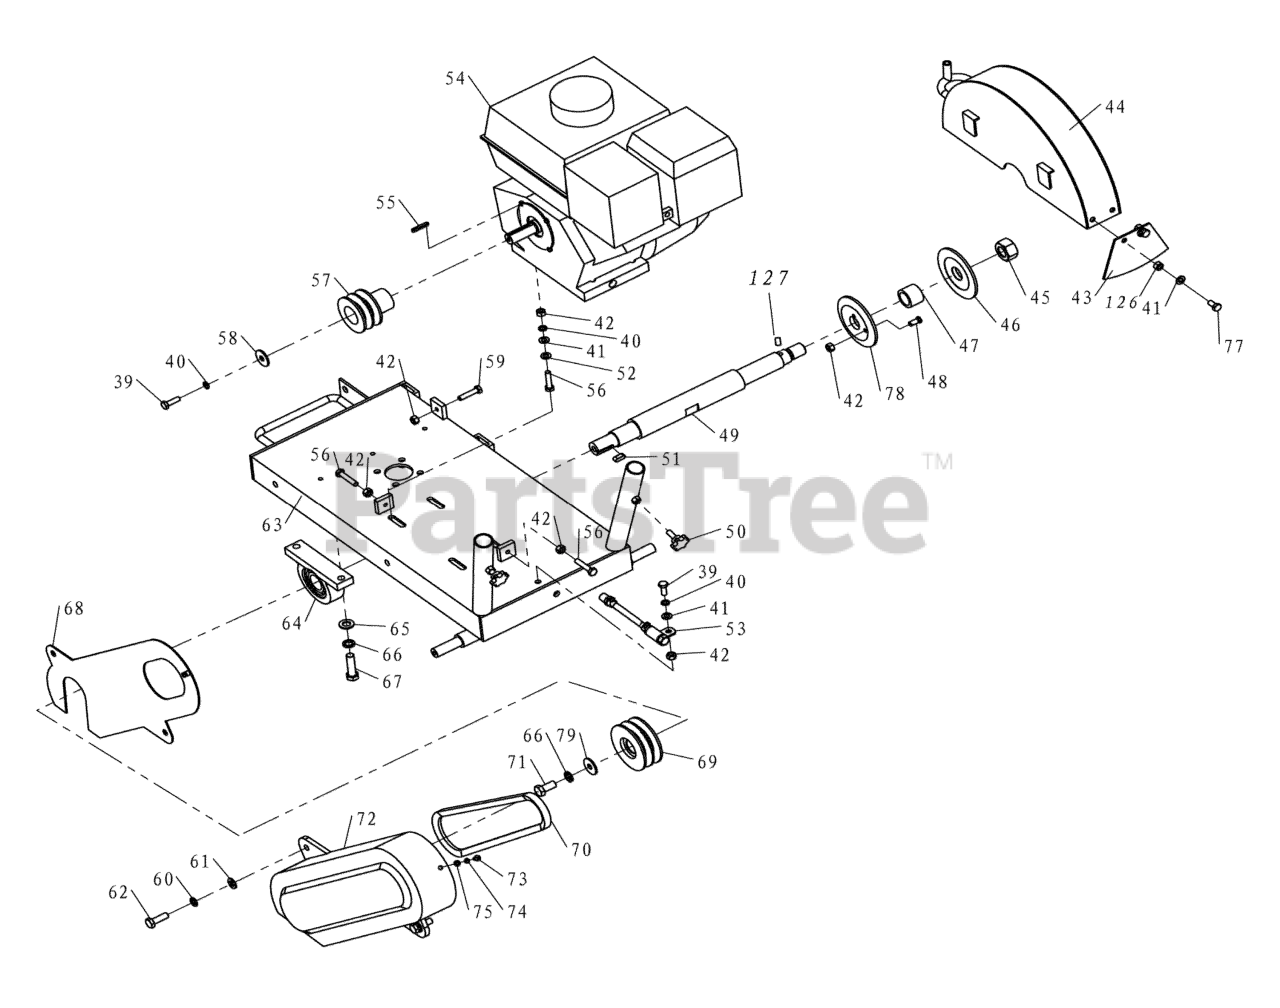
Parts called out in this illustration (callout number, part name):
39	BOLT, M8 x 25
40	WASHER, Spring, 8
41	WASHER, Flat, 8
42	NUT, M8
43	FENDER, Rubber
44	COVER, Blade
46	BLADE FLANGE
47	BUSHING, Blade
48	BOLT, Blade Location
50	KNOB BOLT
52	WASHER
53	DRAIN PIPE ASSEMBLY
54	ENGINE, Briggs & Stratton
56	BOLT, M8 x 45
57	PULLEY, Engine
58	KEY, Bushing
59	NUT, M10
60	WASHER, Spring, 10
61	WASHER, Flat, 10
62	BOLT, M10 x 30
63	BASE PLATE
64	BEARING, NSK206
65	WASHER, Flat, 12
66	WASHER, Spring, 12
67	BOLT, M12 x 45
68	COVER, Belt, Inner
69	PULLY, Belt
71	BOLT, M12 x 25
72	COVER, Belt, Outer
73	SCREW, Cross Recess Head
74	WASHER, Spring, 6
75	WASHER, Flat, 6
78	BLADE FLANGE
79	WASHER, Blade Shaft
126	NUT, Nylon, M8
127	PIN, 6 x 12
